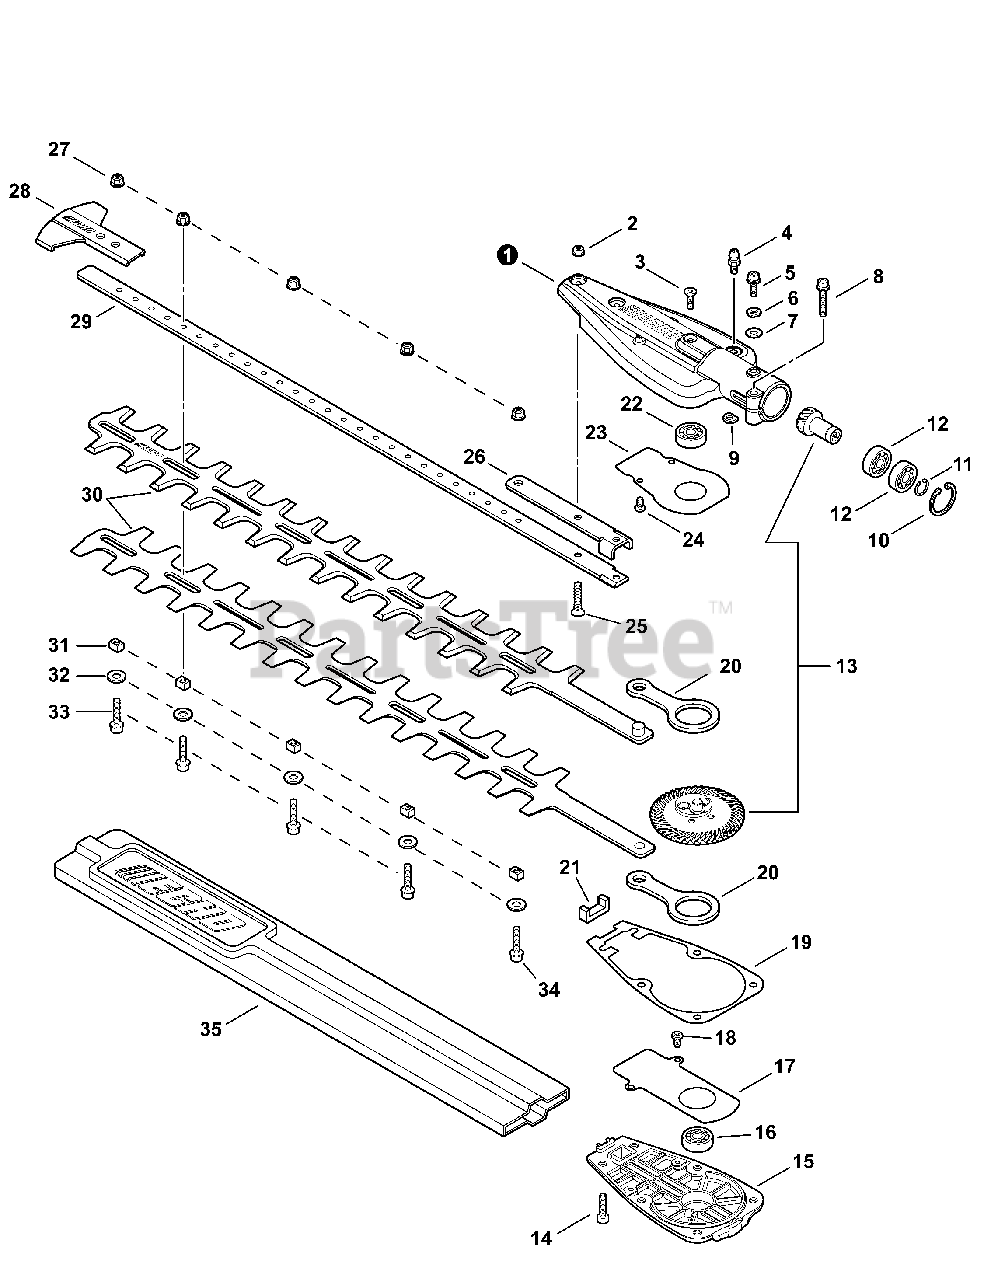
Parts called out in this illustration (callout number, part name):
1	HOUSING, GEAR CASE
2	NUT, FLANGE M5
3	SCREW 5×5/8" HD-SOCKET
4	FITTING, GREASE
5	BOLT, TORX 5×12
6	WASHER, SPRING 5
7	WASHER, FLAT 5.5×10×0.8
8	BOLT, TORX 5×25
10	RING, RETAINING Ø24
11	RING, SNAP Ø12
12	BEARING, BALL
13	GEAR SET
14	BOLT 5×12
15	COVER, GEAR CASE
16	BEARING, BALL 628ZZ
17	GASKET, GEAR CASE
18	SCREW 4×5
19	PLATE, WEAR
20	ROD, CONNECTING
22	BEARING, BALL 608ZZ
23	PLATE, WEAR
24	SCREW 4×5
25	SCREW 5×18
26	SUPPORT, BLADE
27	NUT, FLANGE M5
28	GUARD, TIP
29	SUPPORT, BLADE
31	GUIDE, BLADE 5
32	WASHER 5
33	BOLT 5×20
34	BOLT, FLANGE 5×22
35	SCABBARD
